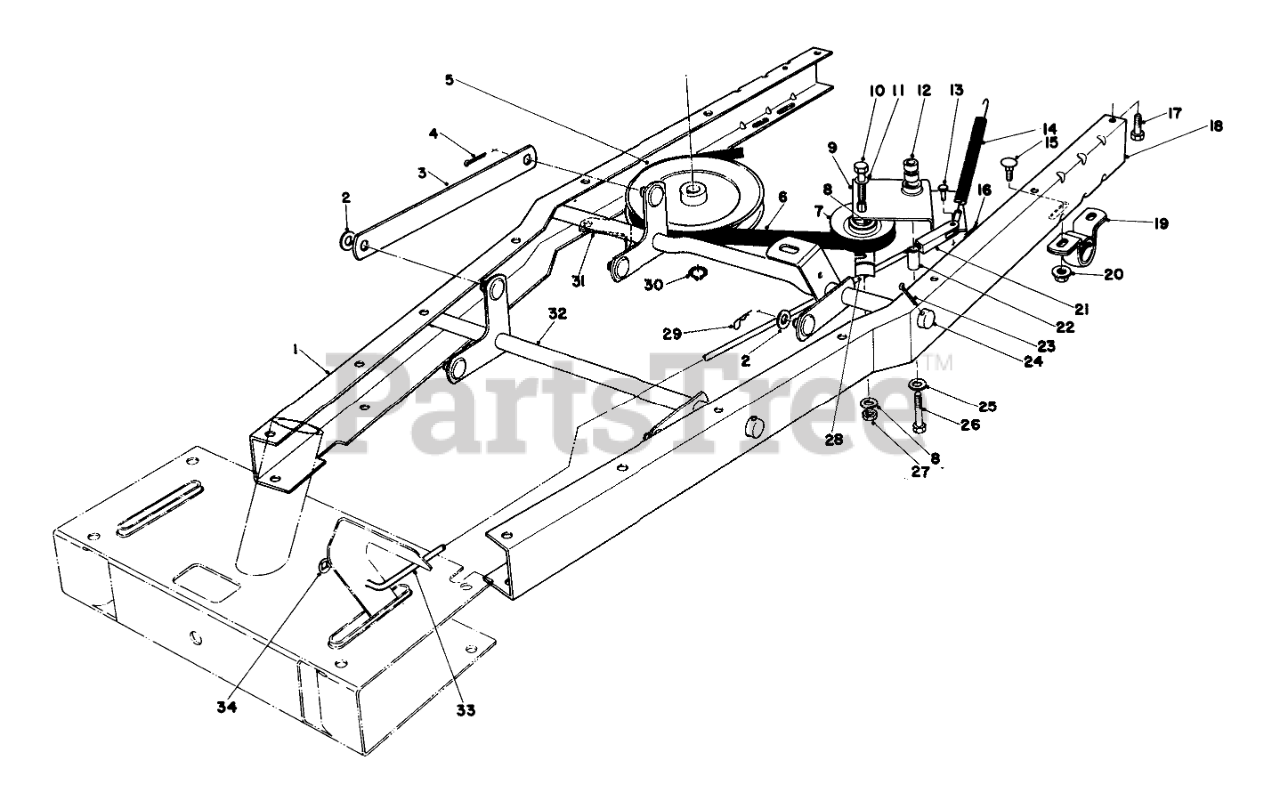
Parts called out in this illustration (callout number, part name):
1	Frame-Channel R.H.
2	WASHER-FLAT
3	Linkage-Height Adj.
4	PIN-COTTER
5	PULLEY
6	V-BELT
7	PULLEY-IDLER
8	WASHER-FLAT
9	Traction Idler (Incl. Ref. #12)
10	SCREW-HH
11	WASHER-FLAT
12	Bushing
13	PIN-CLEVIS
14	Clutch Tension Spring
15	SCREW-CARR
16	PIN-COTTER
17	SCREW-HH
18	LH FRAME CHANNEL B
19	PILLOW BLOCK
20	NUT-HF
22	PIVOT SPACER
23	PIN-COTTER
24	REAR HT ADJ WA B
25	WASHER-PLAIN
26	SCREW-HH
27	NUT-LOCK, SIDE
28	RETAINER-BELT
29	PIN-COTTER
30	RING-SNAP, EXTERNAL
31	TRANS BELT RET B
32	FRONT LIFT WA B
33	Clutch Rod
34	PUSH ON SPEED NUT 1/4
